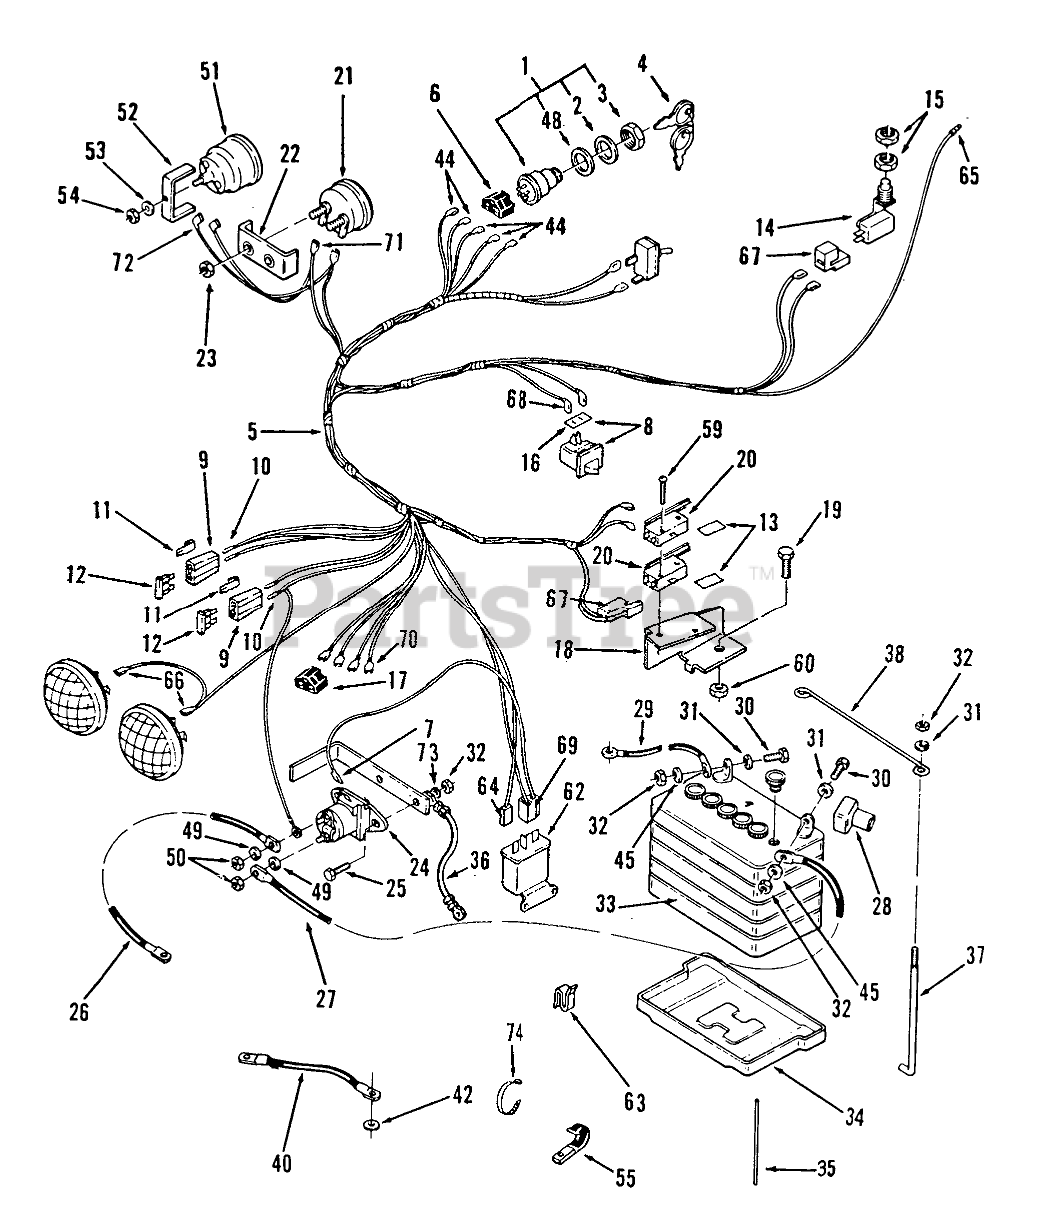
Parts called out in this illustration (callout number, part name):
1	IGNITION SWITCH ASM
2	LOCKWASHER
4	Ignition Key
5	Wiring Harness Assembly 310, 312, 414
6	CONNECTOR-5 WAY-SERV
7	TERMINAL 10
8	SWITCH INTERLOCK
9	AUTO-FUSEBLOCK TERM
10	TERMINAL FUSE
12	FUSE-BLADE, 15 AMP
13	BARRIER - SWITCH
14	Seat Switch
15	NUT-HEX, SPECIAL
16	SHIELD-DIRT SPST
17	BRAKE BAND
18	BRACKET-SWITCH
19	Bolt
20	SWITCH
21	Voltmeter (w/109650)
22	CLAMP MOUNTING
23	HEX NUT 10-32 E.S.
24	Solenoid
25	Bolt
26	ASSY WIRE
27	CABLE-BLACK
28	Boot
29	ASSY WIRE
30	Bolt
32	Nut
33	Battery
34	TRAY-BATTERY
35	TUBE-21" BATTERY DRAIN
36	GROUND-WIRE
38	HOLDDOWN-BATTERY
40	WIRE GROUND
42	Washer-Lock
44	Terminal
45	Washer
48	Washer
50	Nut
51	Hourmeter Complete (includes items 52, 53 & 54)(Not on All units)
52	BRKT-GAUGE MOUNTING
53	Lockwasher
54	Hex Nut
55	CLIP
59	Screw
60	NUT HEX 4-40 ELAST
62	Relay
63	CLIP-CABLE
64	TERMINAL 10
65	Sur-Plug
67	CONNECTOR BODY
68	Terminal
69	CONNECTOR BODY B
70	Connector Part of 5
71	TERMINAL-TAB RCPT
72	Terminal Part of 5
73	LOCKWASHER
74	PLASTIC TIE
